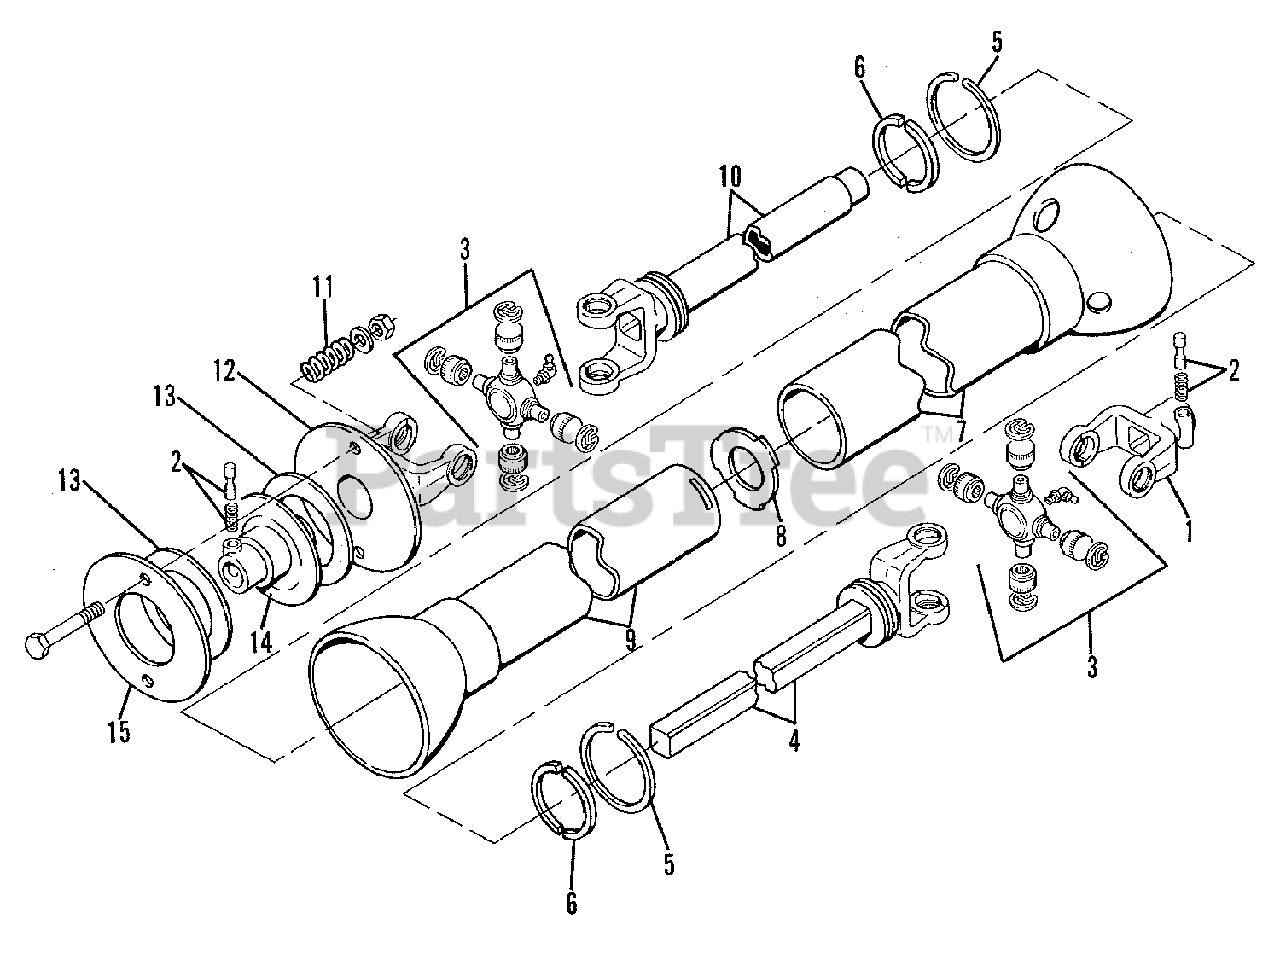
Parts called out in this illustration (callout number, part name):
1	YOKE ASSEMBLY, Tractor End
2	SPRING ASSEMBLY
3	U-JOINT KIT
4	SHAFT ASSEMBLY (Tractor End)
5	RETAINER, Bearing
6	BEARING, Shaft
7	TUBE, Outer Shield
8	CENTRALIZER, Tube
9	TUBE, Inner Shield
10	TUBE ASSEMBLY (Implement End)
11	SPRING, Clutch
11	CAPSCREW, 3/8NC x 3-1/2
11	WASHER, Plain, 7/16 x 1 x 14 Ga.
11	NUT, Lock, 3/8NC
12	YOKE ASSEMBLY, Clutch Plate
13	PLATE, Friction
14	HUB ASSEMBLY
15	PLATE, Large
